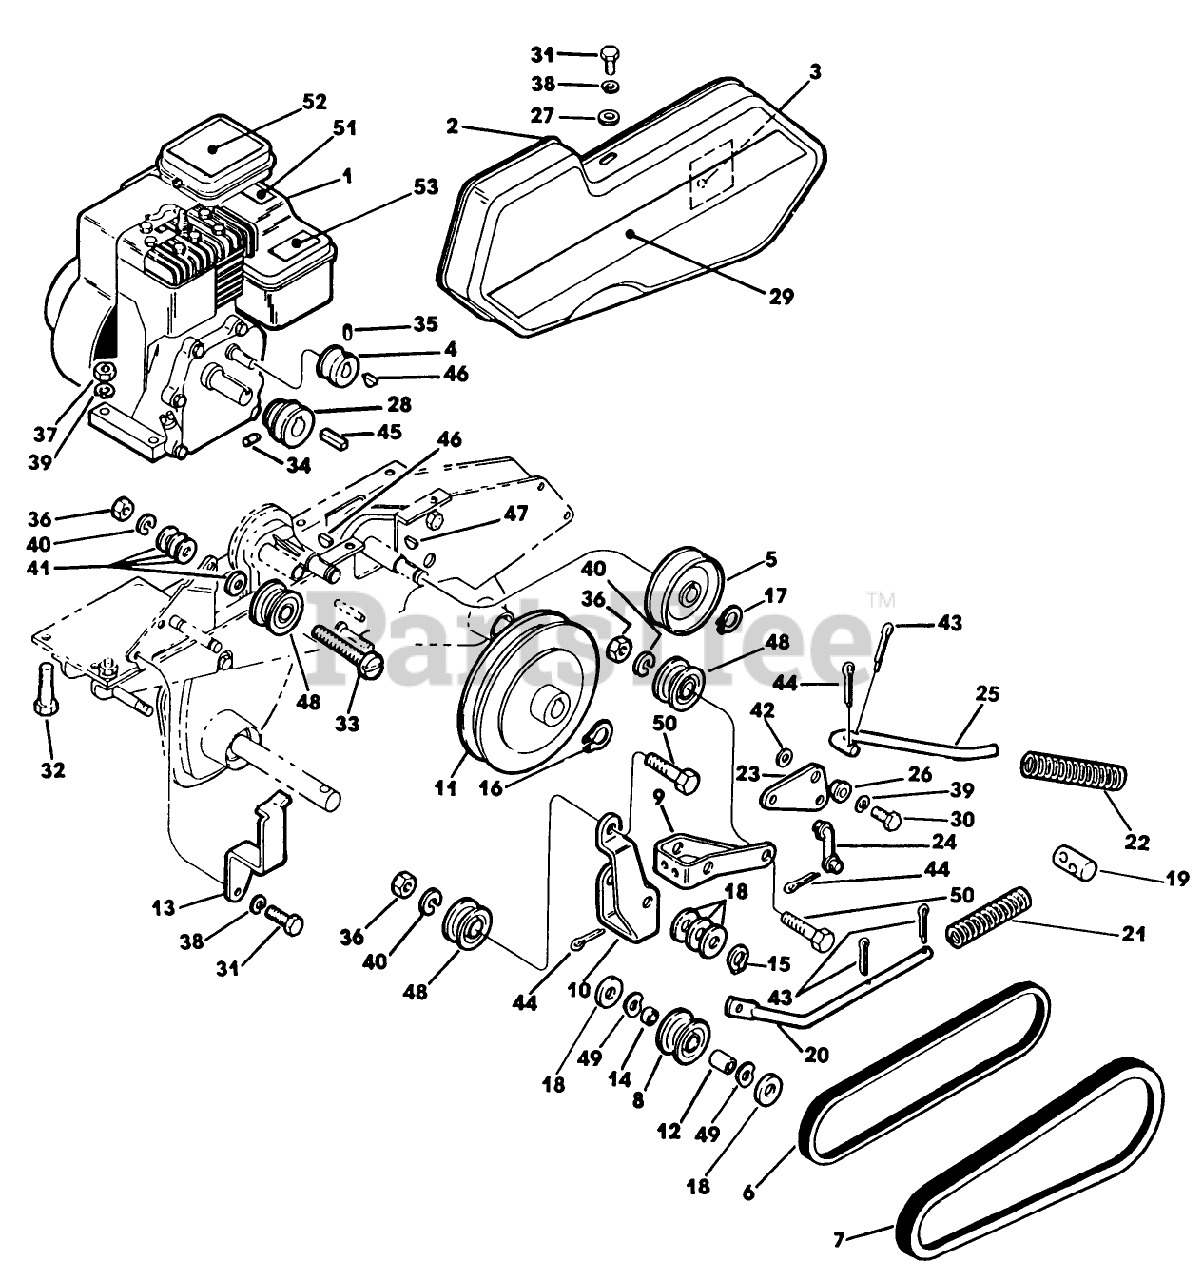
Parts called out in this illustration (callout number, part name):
6	V-BELT
7	TINE DRIVE BELT
17	RING-RETAINING
18	WASHER
19	SWIVEL
30	SCREW - HEX
31	SCREW-HH
34	SET SCREW
36	NUT
37	NUT SS
40	WASHER
41	WASHER
49	WASHER-WAVE
